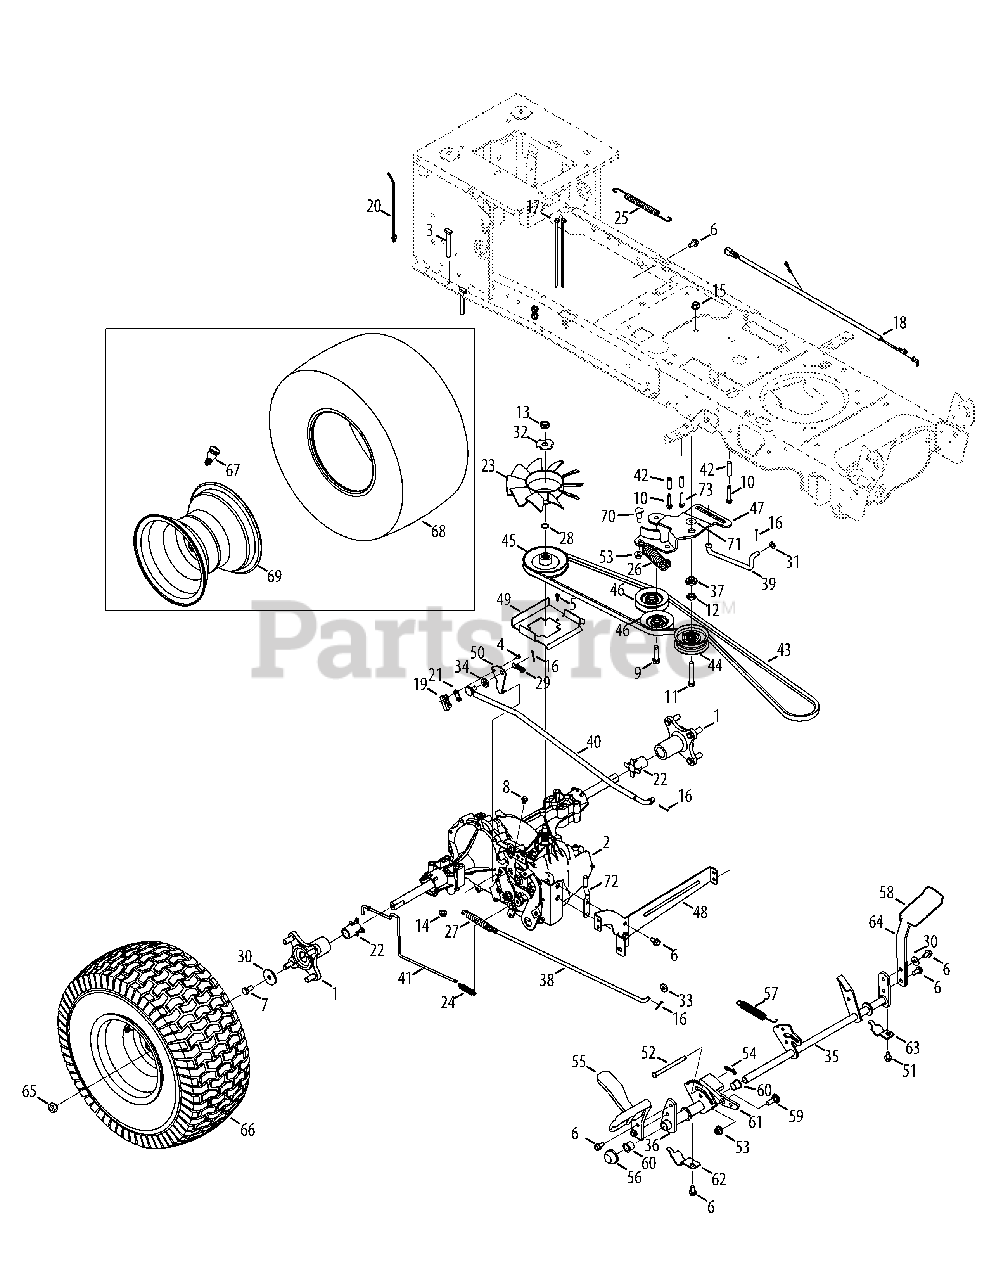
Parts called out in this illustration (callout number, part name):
1	Wheel Hub Assembly
2	Hydro Transmission
3	Hex Head Screw, 5/16-18x2.75
4	Screw, Indented Washer, #8-18x0.500
5	Screw, #10-16:0.500
6	Taptite Screw, 5/16-18x.750
7	Hex Head Screw, 5/16-24x.750
8	Taptite Screw, 1/4-20x0.375
9	Taptite Sems Screw, 3/8-16x1.500
10	Taptite Screw, 1/4-20x1.625
11	Hex Head Screw, 3/8-16x2.25
12	Jam Nut, 7/16-20
13	Jamlock Nut, 1/2-20
14	Flangelock Nut, 5/16-18
15	Flangelock Nut, 3/8-16
16	Cotter Pin, 3/32x1.0
17	Cable Tie. 3/16 x .05 x 7.4
18	Jumper Harness
19	Short Spring Switch
20	Push Mount Cable Tie 7.5 LG
21	Insulator Nut Plate
22	Sleeve, .765 ID x 1.500 LG
23	Hydro Fan
24	Extension Spring, .48 OD x 2.03
25	Extension Spring, .500 DIA x 12.6 LG
26	Extension Spring, 1.00 DIA x 4.75
27	Extension Spring, .59 OD x 4.00 LG
28	Wire Ring
29	Extension Spring, .375 OD x 1.44 LG
30	Bell Washer, .340 x .872 x .060
31	Flat Washer, .330 x .630 x .0635
32	Lock Washer
33	Flat Washer, .344 x .750 x .120
34	Flat Washer, .407 x .812 x .135
35	Brake Control Assembly
36	Hydro Pedal Bracket Assembly
37	Shoulder Spacer, 1.375 x .380 x .183
38	Brake Rod
39	Footpedal Bypass Transmission Rod
40	Hydro Control Rod
41	Hydro Bypass Rod
42	Spacer, 260 x .372 x 1.420 LG
43	V-Belt, 4L x 78.9 POLY
44	Flat Idler Pulley, 2.75 OD
45	Input Pulley, 4.13 DIA
46	V Idler Pulley, x 3.06
47	Center Idler Bracket
48	Hydro Mounting Bracket
49	Belt Disengage Support Bracket
50	Switch Actuator Bracket
51	Taptite Screw, 5/16-18:0.625
52	Clevis Pin, 5/16 x 3.985
53	Flangelock Nut, 3/8-16
54	Bow-Tie Cotter Pin
55	Control Pedal
56	Push Cap
57	Extension Spring, .63 DIA x 4.95 LG
58	Brake Pedal Pad
59	Shoulder Bolt, .500 x .270:3/8-16
60	Flange Bearing, .630 ID x .695 OD x .60
61	Cruise Latch
62	Pedal Support Bracket
63	Pedal Support Bracket, 5/8
64	Brake Pedal Bracket
65	Lug Nut
66	Wheel Assembly
67	Tubeless Air Valve
69	Rim Assembly
70	Screw, Shldr, .50 x .685 3/8-16
71	Washer, Flat, .385 x 1.0 x .030
72	Belt Keeper Rod
73	Screw, Self Tapping, 1/4-20 x 1.75
